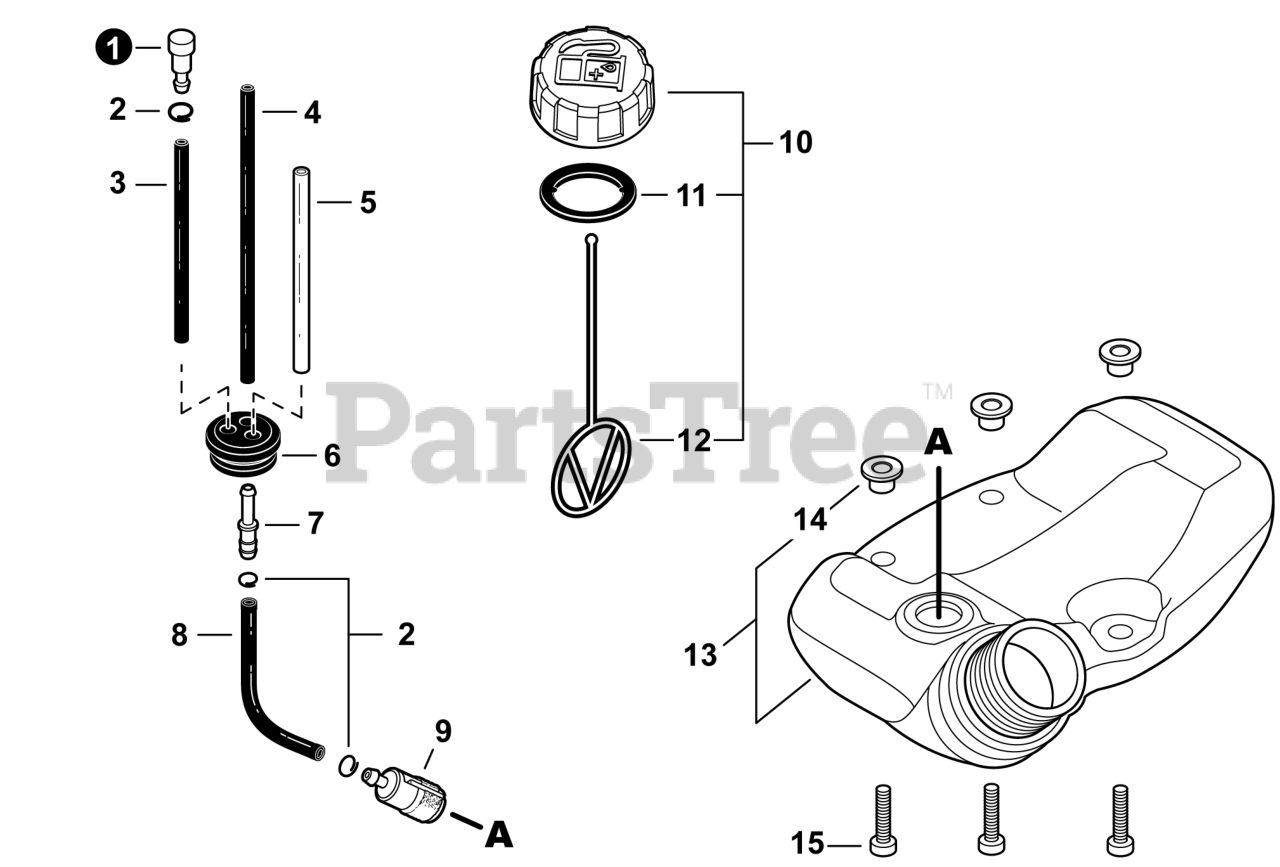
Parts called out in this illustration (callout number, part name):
1	VENT ASSY
3	PIPE, FUEL 3x5x90 BLACK
4	PIPE, FUEL 3x5x74 BLACK
5	PIPE, FUEL 3x6x80 YELLOW
6	GROMMET, FUEL 5
7	CONNECTOR, PIPE 5x3.5
8	PIPE, FUEL 3x5x130 BLACK
9	FILTER, FUEL
10	CAP ASSY, FUEL
11	GASKET, FUEL CAP
12	CONNECTOR, CAP L= 123
13	TANK ASSY, FUEL
14	COLLAR 5
15	BOLT, TORX 5x20
